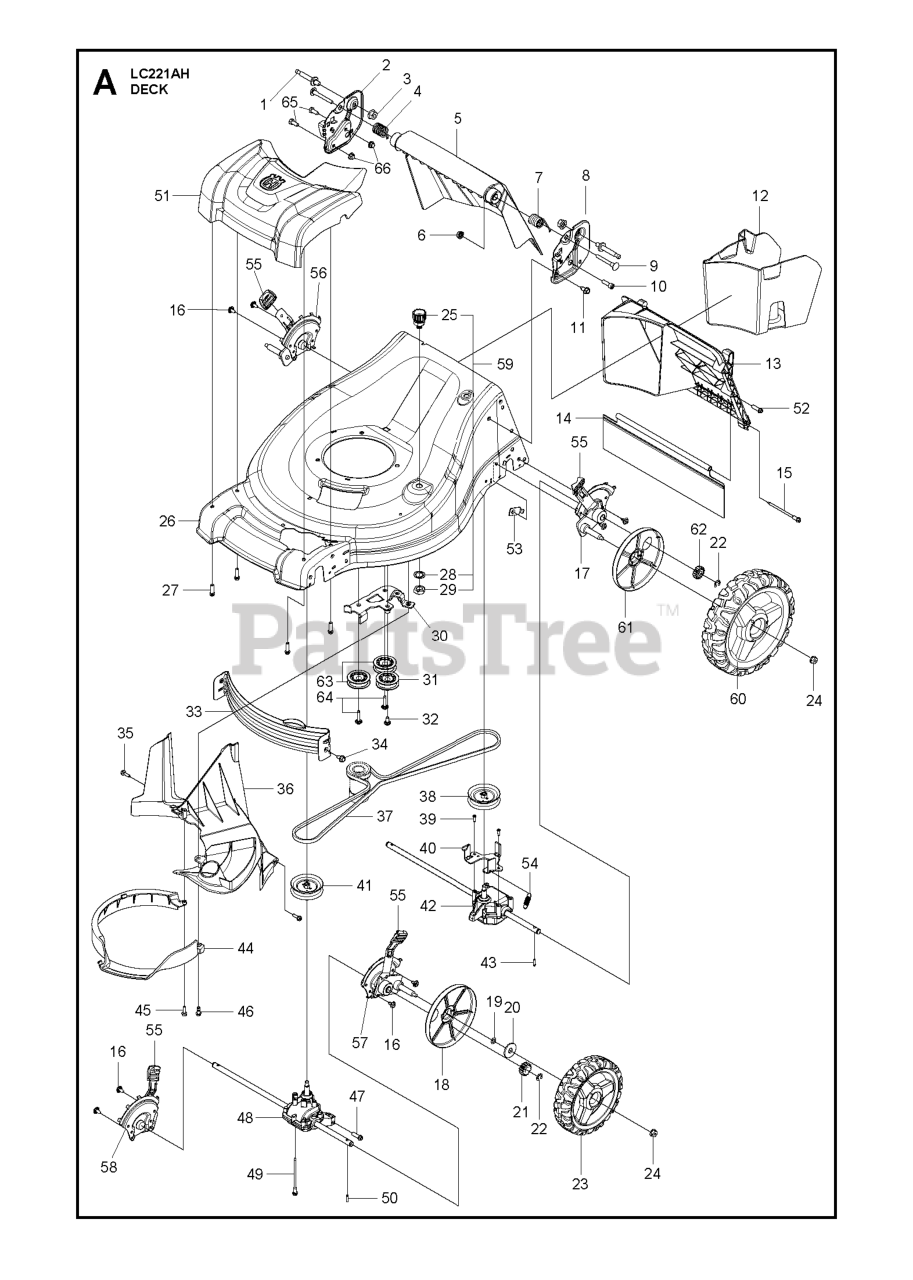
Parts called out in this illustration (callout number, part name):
1	BOLT.HAND.PIVOT.3125-18.21EFF
2	BRACKET.HANDLE.ADJ.21EF.RH.498
3	NUT.FLANGE.SERRAT.3125-18.5625
4	SPRING.RH.DOOR.21 EFF
5	DOOR.REAR.21 EFF.GRY
6	NUT.FLANGED.3/8-16.ZINC
7	SPRING.LH.DOOR.21 EFF
8	BRACKET.HANDLE.ADJ.21EF.LH.498
9	BOLT.DOOR.PIVOT..375-16.21EFF
10	SCREW.HI-LO,5/16-14 X T-45
11	BOLT.5/16HEX.WHS.HD
12	PLUG.MULCH.21 EFF
13	INSERT.REAR.21 EFF
14	SKIRT.REAR.21 EFF
15	SCREW.HI-LO.5/16-14 X 4.10
16	SCREW
17	ADJUSTER.4PT.21EFF.LR.HW.BK
18	COVER.DUST.WHEEL.INNER.WALK
19	O-RING..070X.487.NEOPRENE
20	WASHER FLUT
21	PINIION.14.TOOTH.RGD
22	E-RING 7/16 RE
23	WHEEL.8".AWD.3SP.EXT.DR.GREY
24	NUT.HEX.FLANGE.3/8-16.LO(3 2)
25	FITTING, HOSE, WATER WASHOUT
26	KIT.HSG.21EFF.AWD.WO.668.CE SY
27	SCREW.HI-LO. 5/16 X 1.00
28	WASHER.LOCK.INTERNAL.TOOTH
29	LOCKNUT.HEX.WITH.O-RING
30	BRACKET.ASM.IDLR.AWD.21EFF.BZP
31	PULLEY.RWD.IDLER.DBL SEAL
32	SCREW
33	BAFFLE.FRONT.21 EFF
34	BOLT.5/16HEX.WHS.HD
35	SCREW.HI-LO.13-16X.750.375XDRV
36	COVER.BELT/REAR BAFFLE.21 EFF
37	BELT.DRIVE.21EFF.AWD
38	PULLEY.DRIVE.SM.AWD/RWD
39	SCREW
40	BRACKET.TRAN.BELTKEEPER.22+RGD
41	PULLEY.DRIVE.SM.AWD/RWD
42	TRANSMISSION.AWD.REAR.21EFF
43	PAWL, DRIVE
44	RING.STRIPPER.21 EFF
45	SCREW.HI-LO.13-16X.750.375XDRV
46	BOLT SHOULDER_1/4-20_TRILOB
47	SCREW.HI-LO. 5/16 X 1.00
48	TRANSMISSION.AWD.FRONT.21EFF
49	SCREW.HI-LO.5/16-14 X 4.10
50	PAWL, DRIVE
51	COVER.DR.FULL.HUSQ.21EFF.AWD
52	SCREW.HI-LO,5/16-14 X T-45
53	STRAP.PLATE ATTACH.21 EFF.GLV
54	SPRING.RETURN.AUTO.
55	SELECTOR KNOB
56	ADJUSTER.4PT.21EFF.RR.HW.BK
57	ADJUSTER.4PT.21EFF.LF/RR.BLK
58	ADJUSTER.4PT.21EFF.RF/LR.BLK
59	KIT.WASH-OUT.PORT
60	WHEEL.11.H3SP.AWD.LC.460.BB2
61	COVER.DUST.WHEEL.HW.AWD.REAR
62	PINION.16.TEETH.HW.AWD.REAR
63	PULLEY.ASM.22+ AWD
65	BOLT.FIN.HEX.5/16-18X3/4
66	NUTNYLOK.FLRANGE.5/16-18
